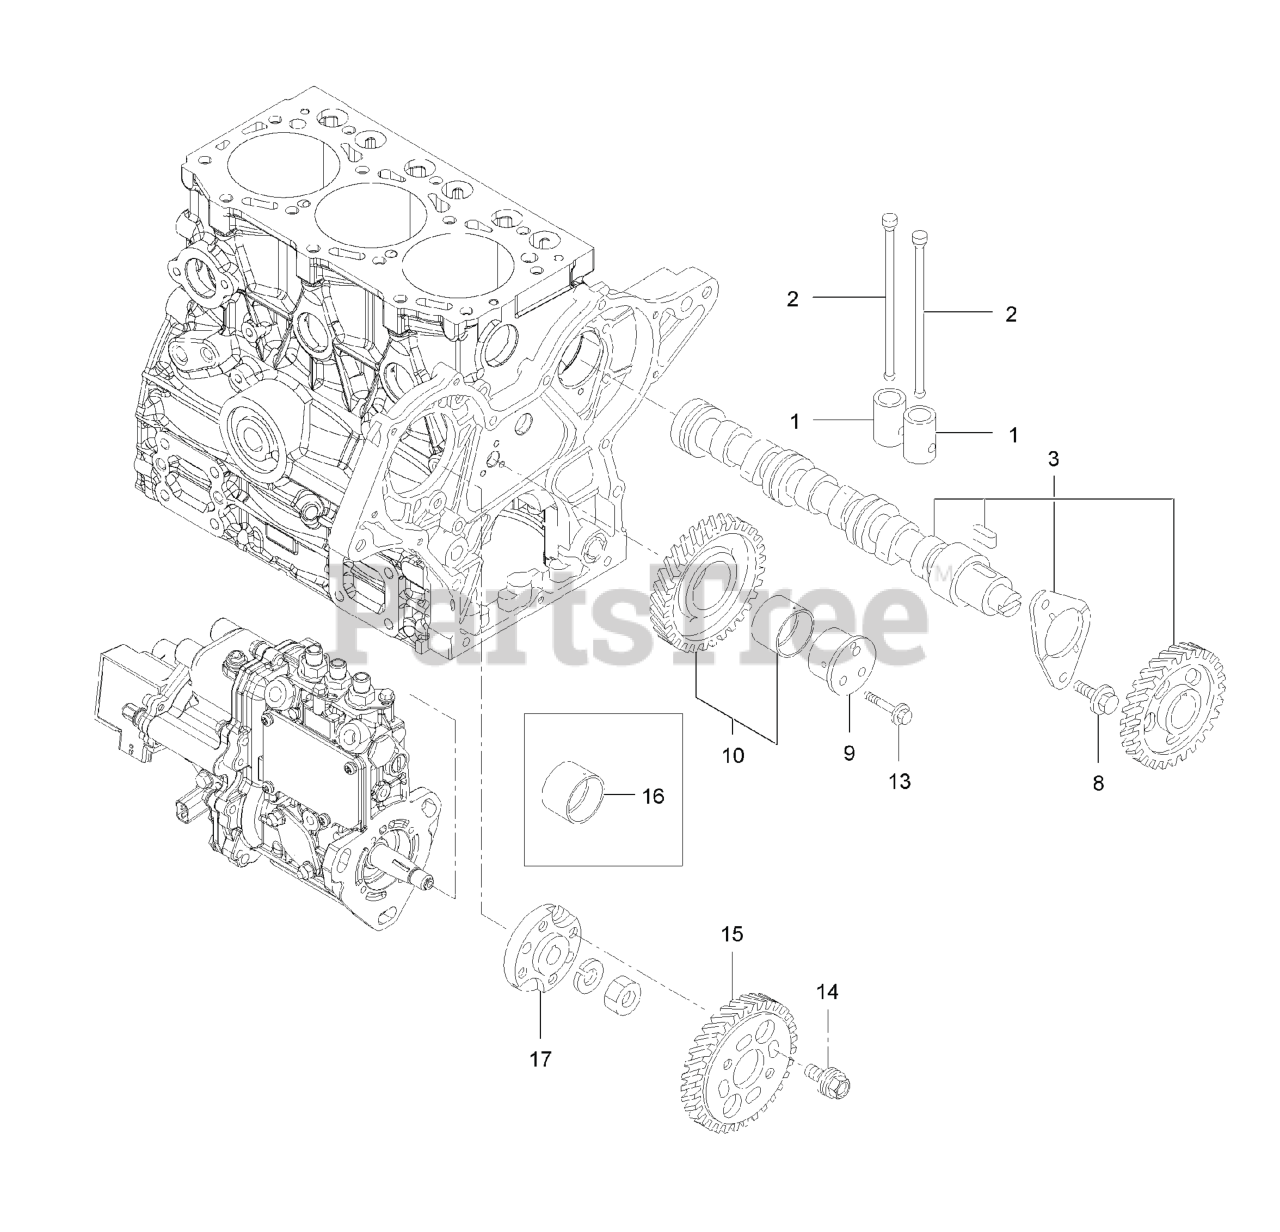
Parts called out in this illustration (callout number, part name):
2	PUSH-ROD
3	CAMSHAFT ASM
9	SHAFT-IDLE
10	GEAR ASSY-IDLE
15	GEAR-PUMP
16	BUSH-IDLE GEAR
